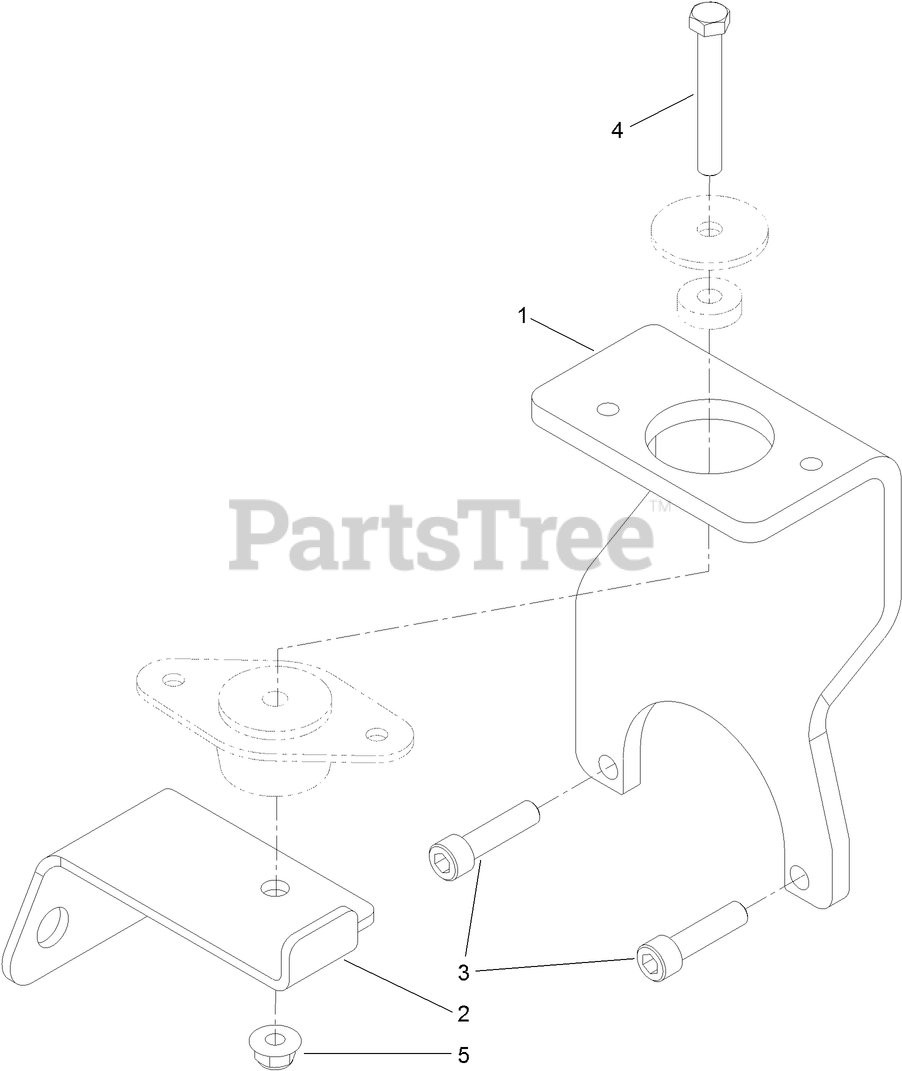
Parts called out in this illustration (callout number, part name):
1	BRACKET-SUPPORT, PUMP
2	BRACKET-BULKHEAD
3	SCREW-SH
4	SCREW-HH
5	NUT-HF, NI
